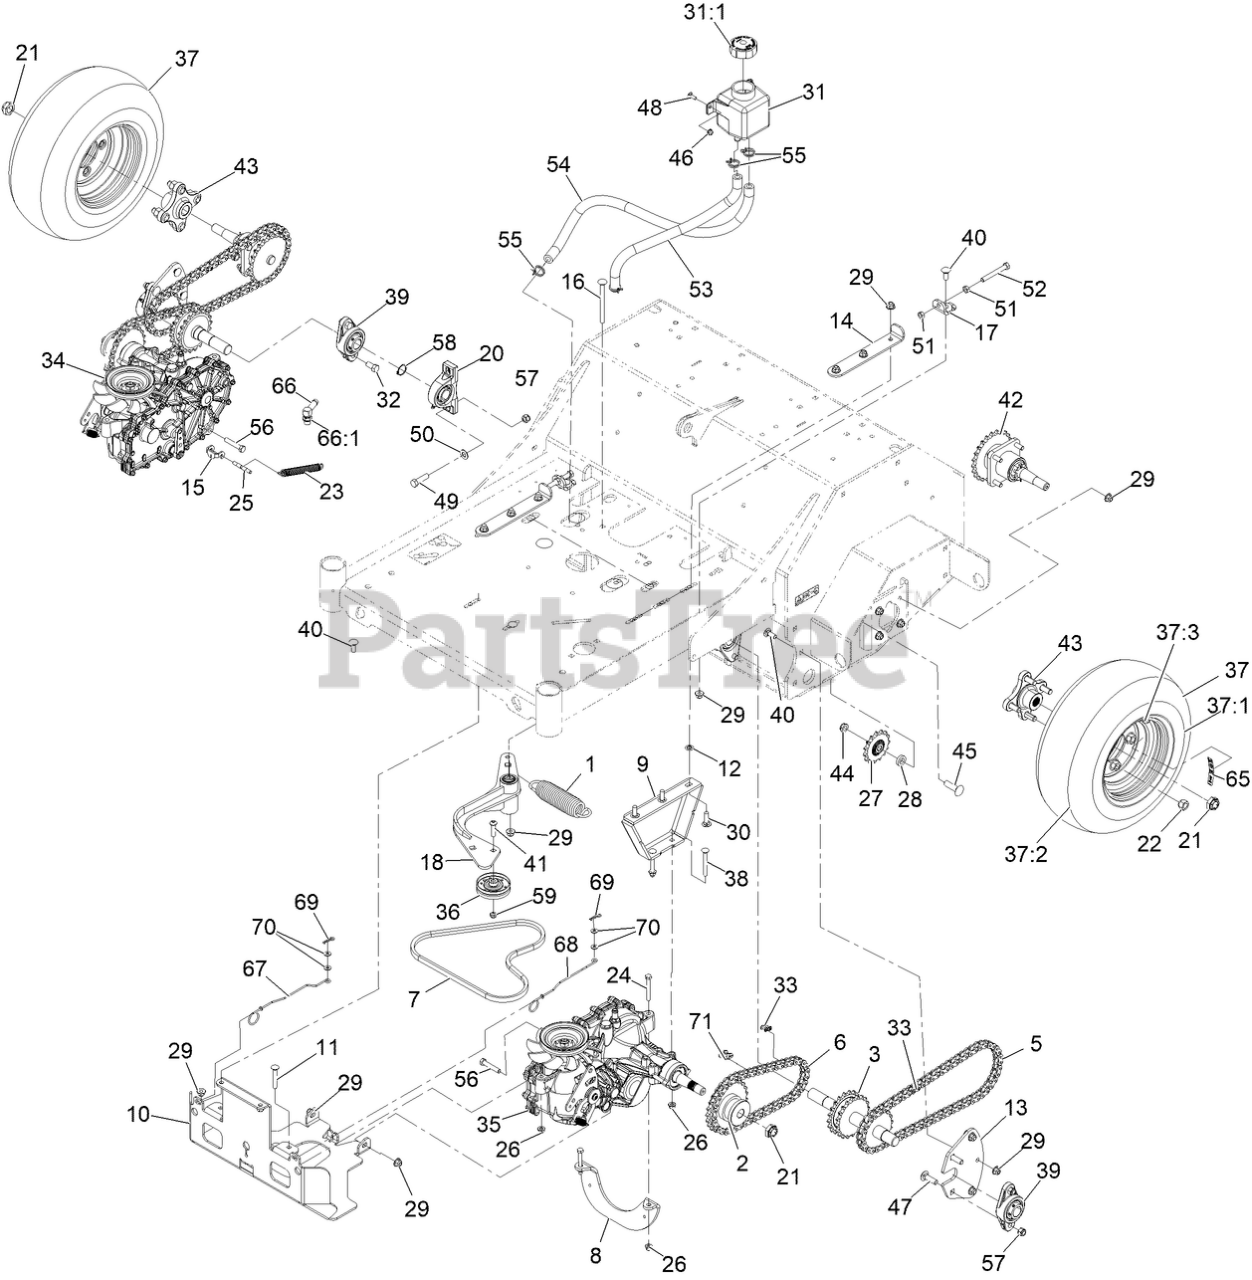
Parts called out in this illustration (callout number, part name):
1	SPRING-EXTENSION
2	HUB-DRIVE, CHAIN
3	JACKSHAFT
5	CHAIN-ROLLER
6	CHAIN-ROLLER
7	BELT-4L SECTION
8	Brace-Angle
9	MOUNT-TRANSMISSION
10	GUARD-TRANSMISSION
11	BOLT-CARR
12	NUT-PUSH
13	Plate-Jackshaft
14	PLATE-ADJUSTMENT, TRANSMI
15	YOKE-BRAKE, PARK
16	BOLT-CARR
17	BRACKET-HYDRO, ADJUST
18	IDLER ARM ASM
20	BEARING-PILLOW BLOCK
21	NUT-LOCK
22	NUT-LUG
23	SPRING-DOOR
24	SCREW-HH
25	PIN-BRAKE, PARK
26	NUT-HF, NI
27	SPROCKET-IDLER, 15T
29	NUT-HF, NI
30	BOLT-CARR
31	TANK-HYD
31:1	CAP-RESERVOIR, HYD
32	SCREW-HH
33	LINK-CONNECTING
34	TRANSAXLE-ZT3100, RT (W/P
35	TRANSAXLE-ZT3100, LT (W/P
36	PULLEY-IDLER
37	Tire ASM (16 X 6.50-8)
37:1	RIM-8X5.375, CENTERED
37:3	Stem-Valve
38	SCREW-CARR
39	BEARING-FLANGE, 2 BOLT
40	BOLT-CARR
41	SCREW-HSBH
42	AXLE AND BEARING ASM
43	HUB-OFFSET
44	NUT-HEX
45	SCREW-CARR
47	BOLT-CARR
48	BOLT-CARR
50	WASHER-FLAT
51	NUT-HEX
52	SCREW-HH
53	HOSE-HYDRAULIC
54	HOSE-HYDRAULIC
55	CLAMP-HOSE
56	SCREW-HH
57	NUT-LOCK, NI
58	RING-RETAINING
65	DECAL-HUB, WHEEL
66	FITTING-ELBOW, 90
66:1	O-RING
67	ROD-BYPASS, RH
68	ROD-BYPASS, LH
69	PIN-COTTER
71	LINK-#50 HALF LINK
